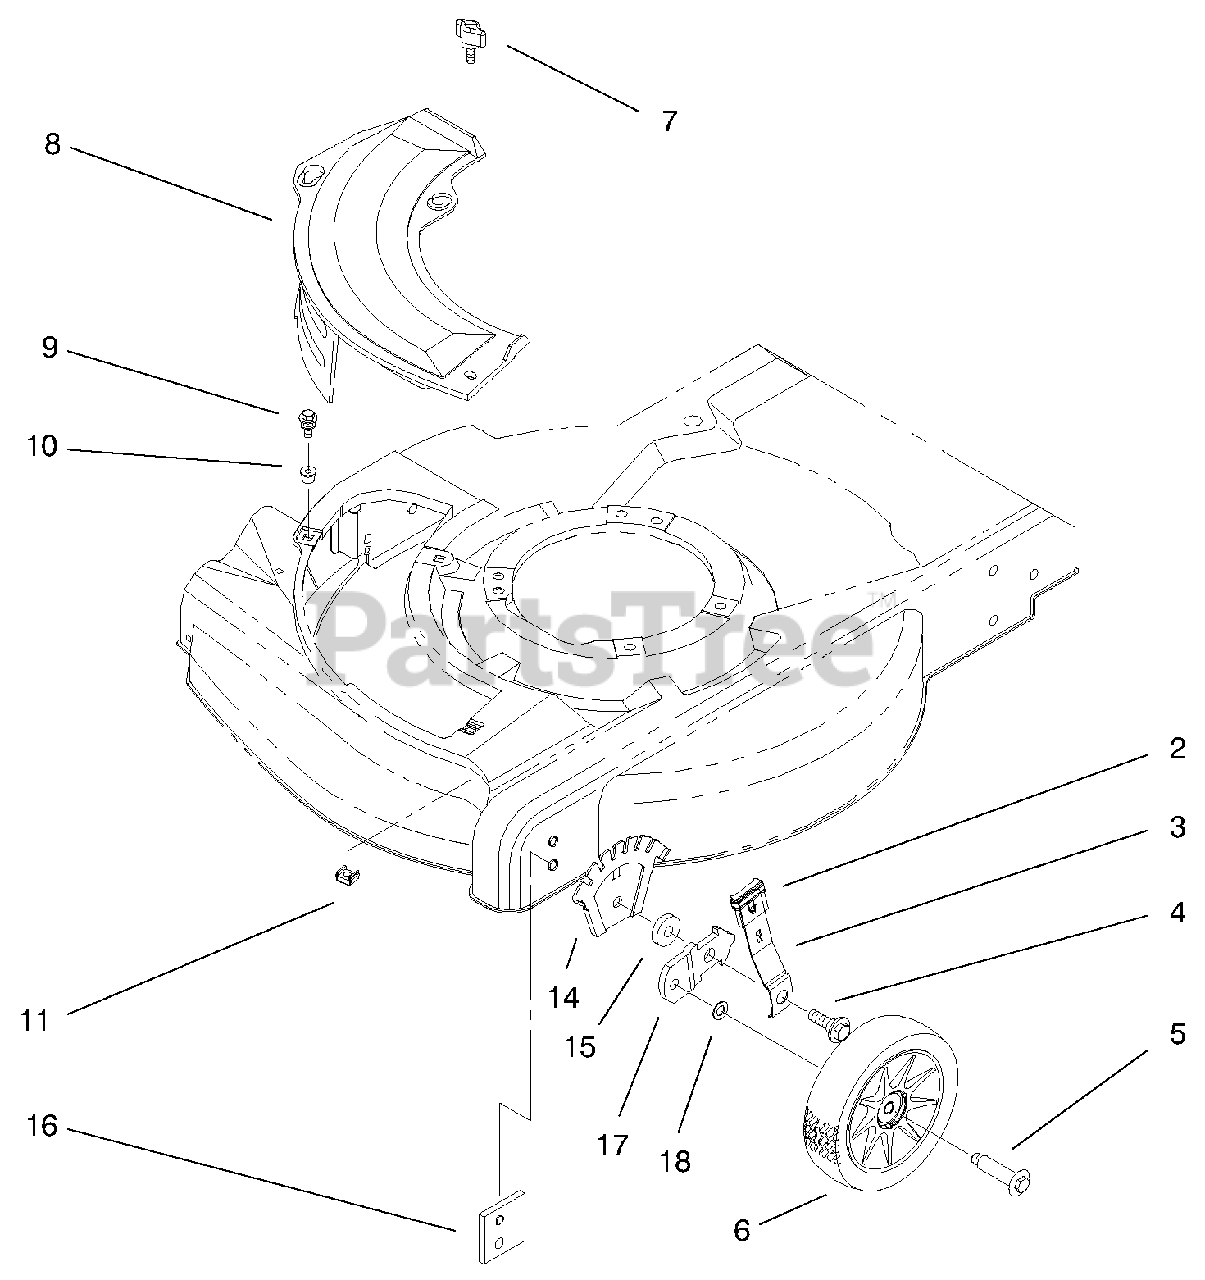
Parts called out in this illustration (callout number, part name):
2	Knob-Height Adjust
3	Spring Arm-Front
4	Bolt-Shoulder
5	Bolt-Shoulder
6	ASM-Wheel & Tire 6"
7	Knob-Cover Plate
8	Mulch Plate-21"
9	Screw-Sems
10	Grommet-Plastic
11	Nut-Cage
14	Plate-Height Adjust
16	Plate-Baffle
17	Bracket-Wheel Height Adj
